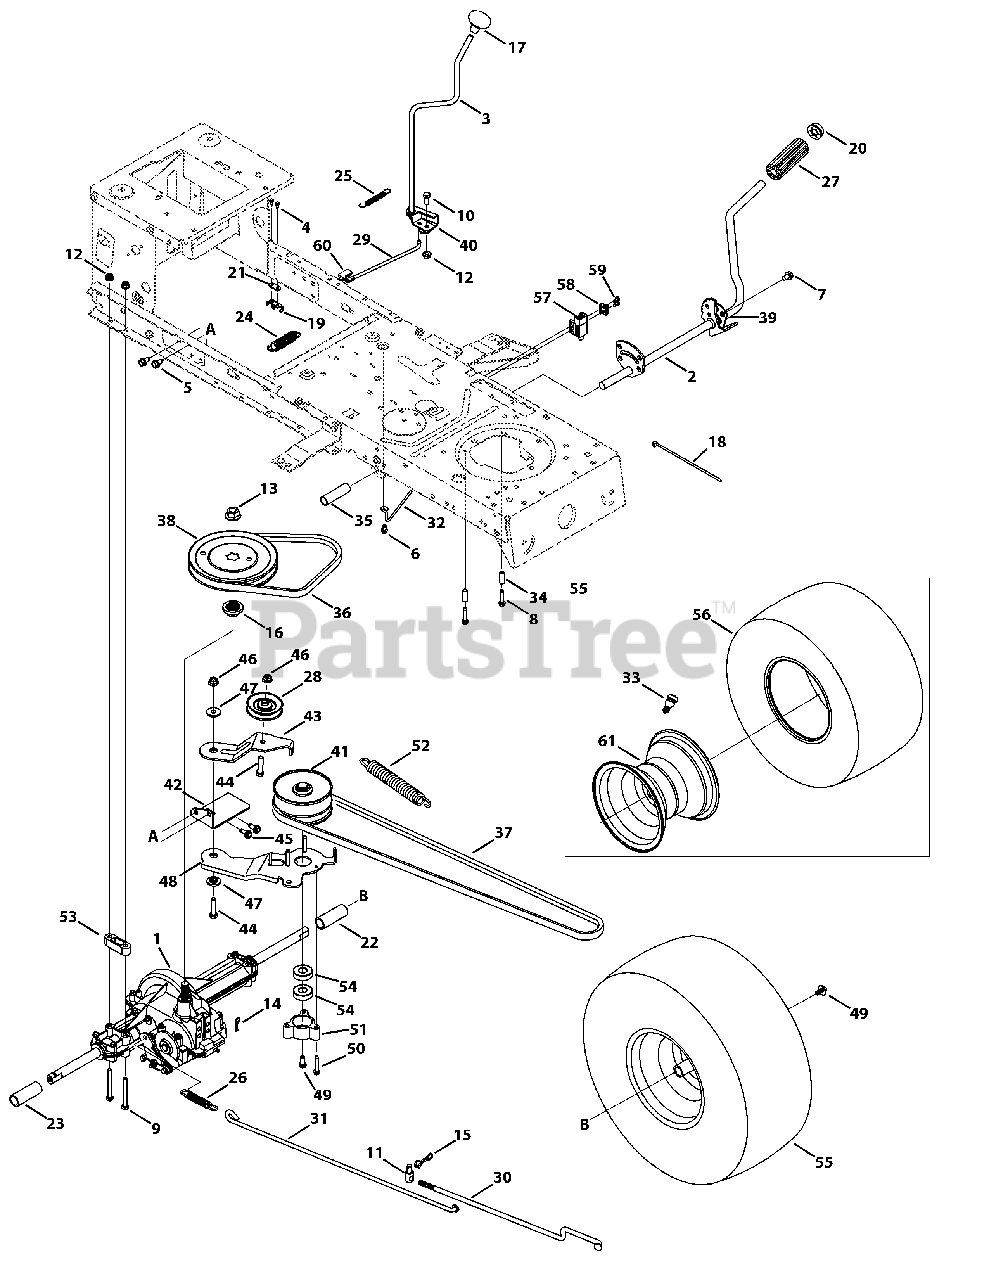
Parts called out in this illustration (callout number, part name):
1	Transmission Drive Assembly
2	Pedal Assembly
3	Shaft Lever Assembly
4	Screw, 8-18:0.500
5	Screw, 5/16-18 x .750
6	Screw, 1/4-20 x 0.500
7	Screw, 5/16-18 x 0.625
8	Screw, 1/4-20 x 1.250
9	Hex Screw, 5/16-18 x 3.50
10	Hex Screw, 5/16-18 x .75
11	Ferrule, 3/8-24 X .375 DIA.
12	Flangelock Nut, 5/16-18
13	Flange Nut, 9/16-18
14	Cotter Pin INT- .125 DIA
15	Bow-Tie Cotter Pin, 72
16	Pulley Hub, 5/8 SPLINE
17	Shift Knob
18	Cable Tie
19	Short Spring Switch
20	Push Cap, 5/8
21	Plate Insulator Nut
22	Sleeve, .758 x .821 x 3.3125
23	Sleeve, .758 x .821 x 2.4375
24	Spring Extension, .80 OD x 3.28 LG
25	Spring Extension, .38 OD x 3.25 LG
26	Spring Extension, .59 OD x 4.00 LG
27	Foot Pad, 4.0 LONG
28	Idler Pulley
30	Variable Speed Control Rod
32	Belt Keeper Rod
33	Valve, tubeless Air
34	Spacer, .260 x .375 x 1.030 LG
35	Spacer, .640 ID x .76 OD x 2.63
36	V Belt, 5L 35.25 POLY
37	V Belt, 5L 70.90 POLY
38	V Pulley 7.25 DIA SPUN
39	Pedal Support Bracket
40	Shaft Adjust Bracket
41	Variable Speed Pulley Assembly
42	Transmission Bracket Assembly
43	Idler Bracket Assembly
44	Hex Screw, 3/8-16 x 1.75
45	Screw, 5/16-18 x 0.750
46	Flangelock Nut, 3/8-16
47	Shoulder Spacer, .625 ID x .169
48	Bracket Assembly
49	Screw, 5/16-24 x .750
50	Screw, 1/4-20 x 1.500
51	Bearing Cup
52	Extension Spring, .94 OD x 6.75 LG
54	Ball Bearing, 17 x 40 x 12
55	Wheel, 20 x 8 x 8
56	Tire, 20 X 8 X 8 Rd Shldr
57	Switch Interlock
58	Plate Switch
59	Shoulder Screw, #10-32 x .500
60	Shift Plate Bearing
61	Rim, 8.0 x 7.0 x .750
